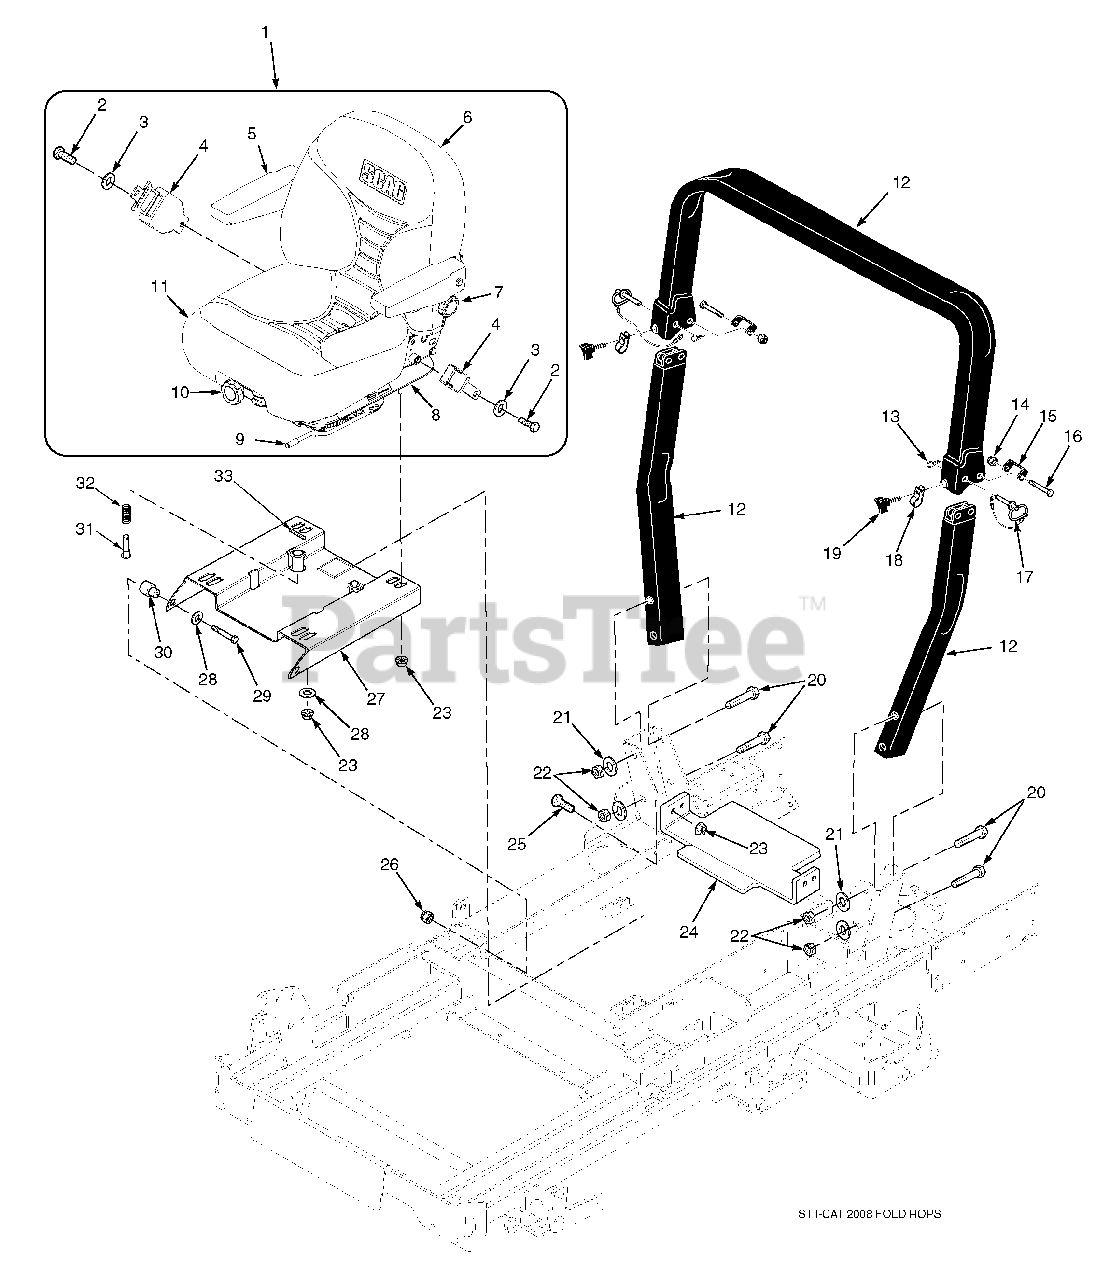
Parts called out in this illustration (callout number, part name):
1	Suspension Seat Assembly w/seat belt
2	Bolt, Hex Head 7/16-20 x 1"
3	Flatwasher, 7/16-.500 x 1.25 x .083
4	Retractable Seat Belt
5	Armrest Only
6	Back Cushion Kit
7	Lumbar Kit
8	Shock Absorber Kit
9	Seat Adjustment, Track Set
10	Weight Adjustment Kit
11	Seat Cushion Kit Seat Drain Kit
12	STT, ROPS Accessory
13	Hair Pin, Cotter
14	Nut, Center Lock 1/2-13
15	Bracket, Stop
16	Bolt, Hex Head 1/2-13 x 3-1/2"
17	Pin
18	Clamp
19	Thumb Screw, 5/16-18 NC x 3/4"
20	Bolt, Hex Head 1/2-13 x 4-1/2"
21	Flatwasher, 1/2-.562 x 1.375 x .109
22	Nut, Center Lock 1/2-13
23	Nut, Serrated Flange 5/16-18
24	Bracket, Seat Hold Down with Decal
25	Bolt, Hex Head 5/16-18 x 1"
26	Nut, Elastic Stop 3/8-16
27	Seat Plate Weldment w/Decal
28	Flatwasher, 3/8-.391 x .938 x .105
29	Bolt, Hex Head 3/8-16 x 2"
30	Spacer Bushing
31	Pin Retainer, Spring
32	Spring, Seat
33	Roll Pin, Spring 5/32 x 3/4"
